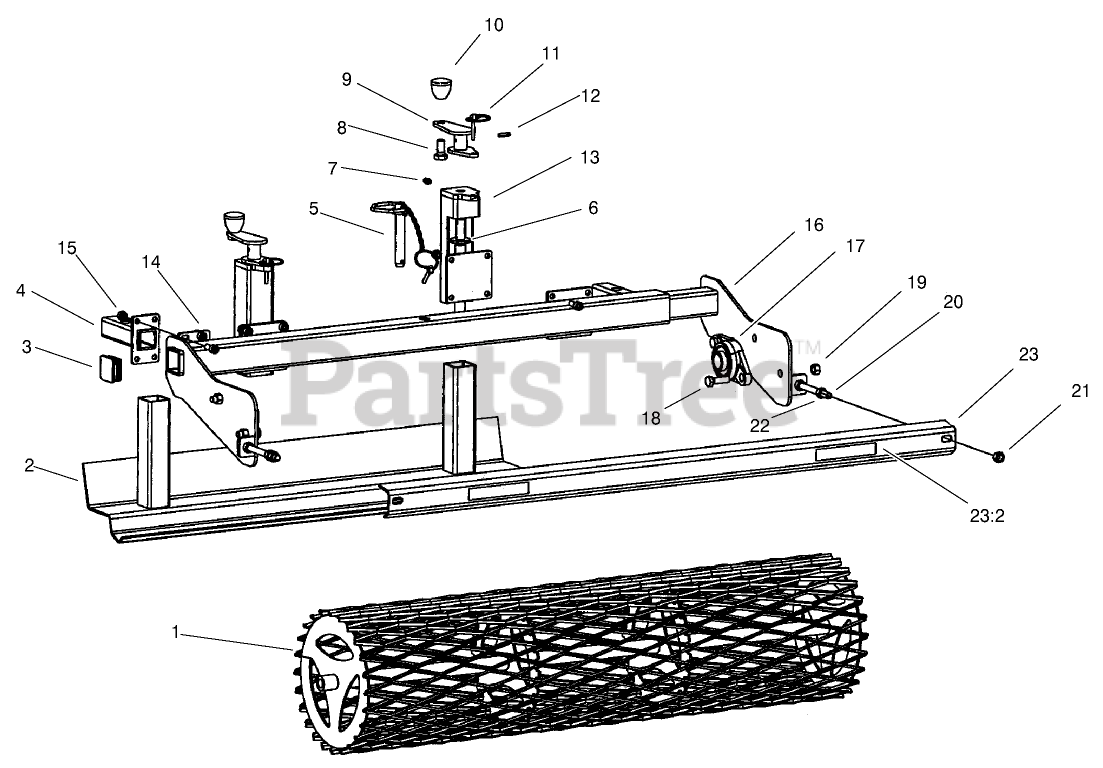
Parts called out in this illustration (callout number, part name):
1	ROLLER-MESH
2	BLADE-GRADER
4	ARM-MALE
5	PIN-DRIFT
7	ZERK-GREASE
8	SCREW-HH
10	HANDLE
11	PIN-LOCKING
13	TUBE-HANDLE, FEMALE
14	SCREW-HSH
15	NUT-LOCK, NI
16	ROLLER FRAME ASM
17	BEARING ASM
18	BOLT-HH
19	NUT-HEX
20	SCREW-HH
21	NUT-LOCK
23	SCRAPER PLATE ASM
23:2	DECAL-WARNING
